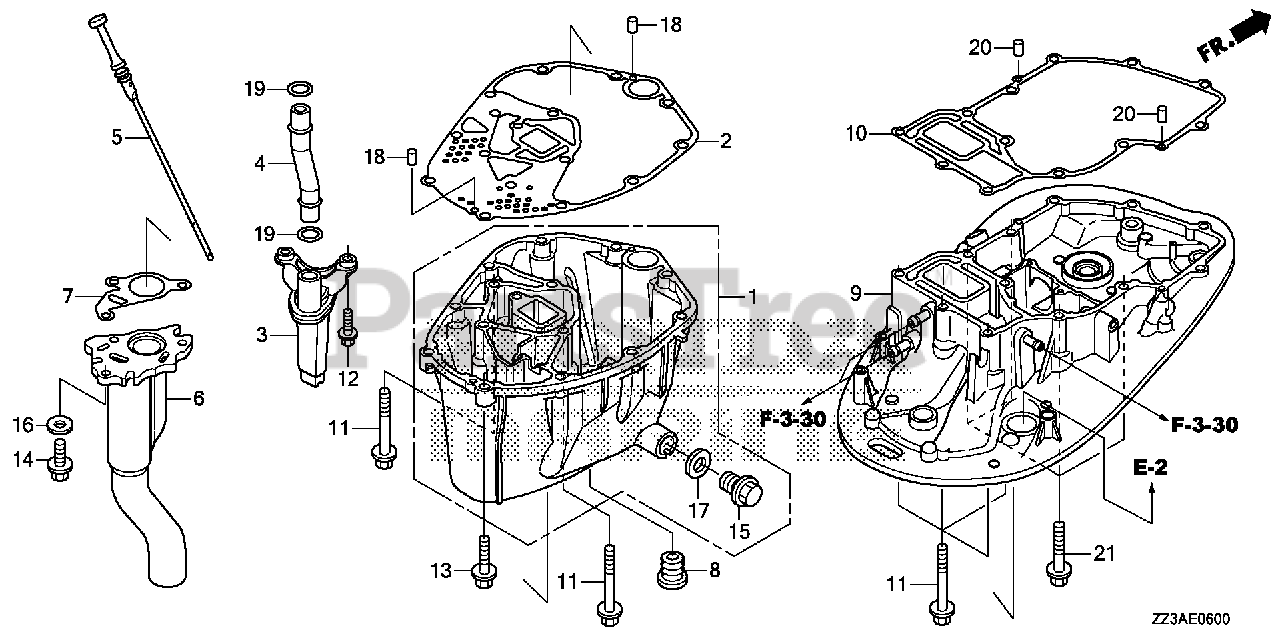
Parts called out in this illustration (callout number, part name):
1	CASE ASSY., OIL *TGRAY* (GRAY)
2	GASKET, OIL PAN
3	STRAINER, OIL
4	PIPE, OIL STRAINER
5	DIPSTICK, OIL
7	GASKET, EX. PIPE
8	GROMMET, WATER TUBE
9	CASE, MOUNT *NH8* (DARK GRAY)
10	GASKET, MOUNT CASE
11	BOLT, FLANGE (8X60) (SUS)
12	BOLT, FLANGE (6X22)
13	BOLT, FLANGE (8X35) (SUS)
14	BOLT, FLANGE (8X26) (SUS)
15	BOLT, DRAIN PLUG
16	WASHER, PLAIN (8MM)
17	WASHER, DRAIN PLUG (12MM)
18	PIN, DOWEL (6X10)
19	O-RING (13X3.0)
20	PIN, DOWEL (6X10)
21	BOLT, FLANGE (8X60)
